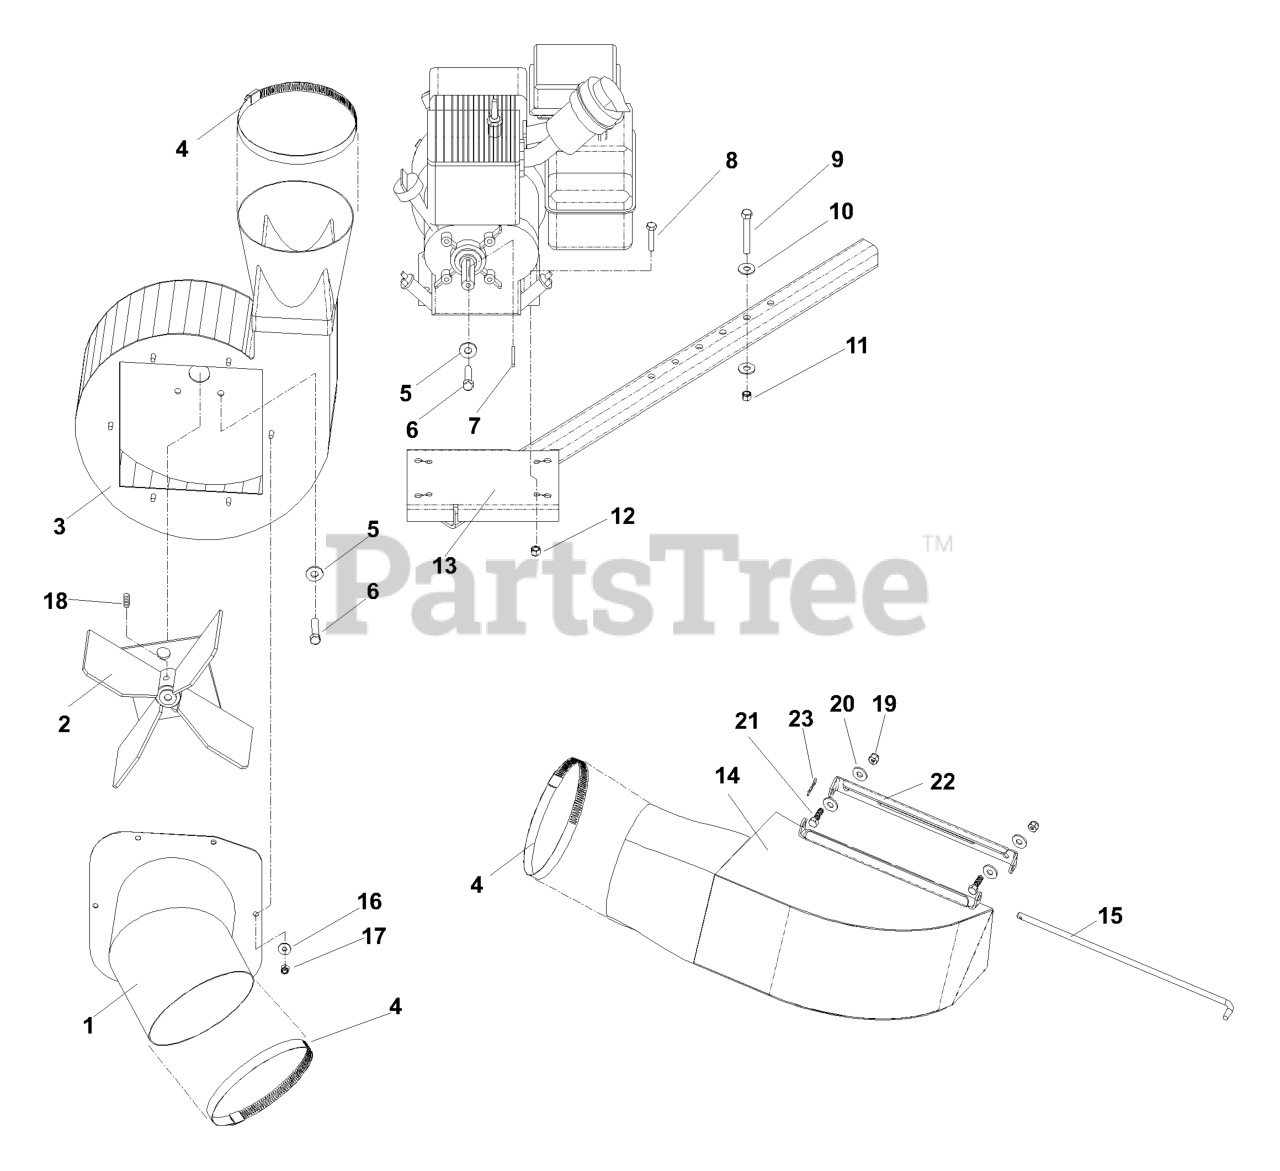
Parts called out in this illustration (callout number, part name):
1	BLOWER HOUSING INLET
3	BLOWER HOUSING
4	HOSE CLAMP
5	R/B 109600 WASH SPRING, 5/16
6	R/B 990233 BLT HEX 5/16-24X3/4
7	KEY SQUARE 3/16 X 3/16 X 1 3/4
8	BOLT, 5/16-18 X 1 1/2
9	HEX BOLT 3/8-16 X 2.5"
10	FLAT WASHER 3/8
11	NUT 3/8 NYLOC
12	HEX NUT - NYLON LOCK 5/16-18
13	ENGINE MOUNT
14	BOOT, GEN II
14	BOOT, GEN I
15	BOOT ROD - 14"
16	WASHER, 1/4
17	NUT, 1/4-20, NYLOC
18	SCREW SET, 3/8-24 X 3/8
19	HEX NUT - NYLON LOCK 5/16-18
20	WASHER, 5/16
21	BOLT, 5/16-18 X 1
22	BRACKET
23	PIN, HAIR COTTER #13 5/64 X 1
